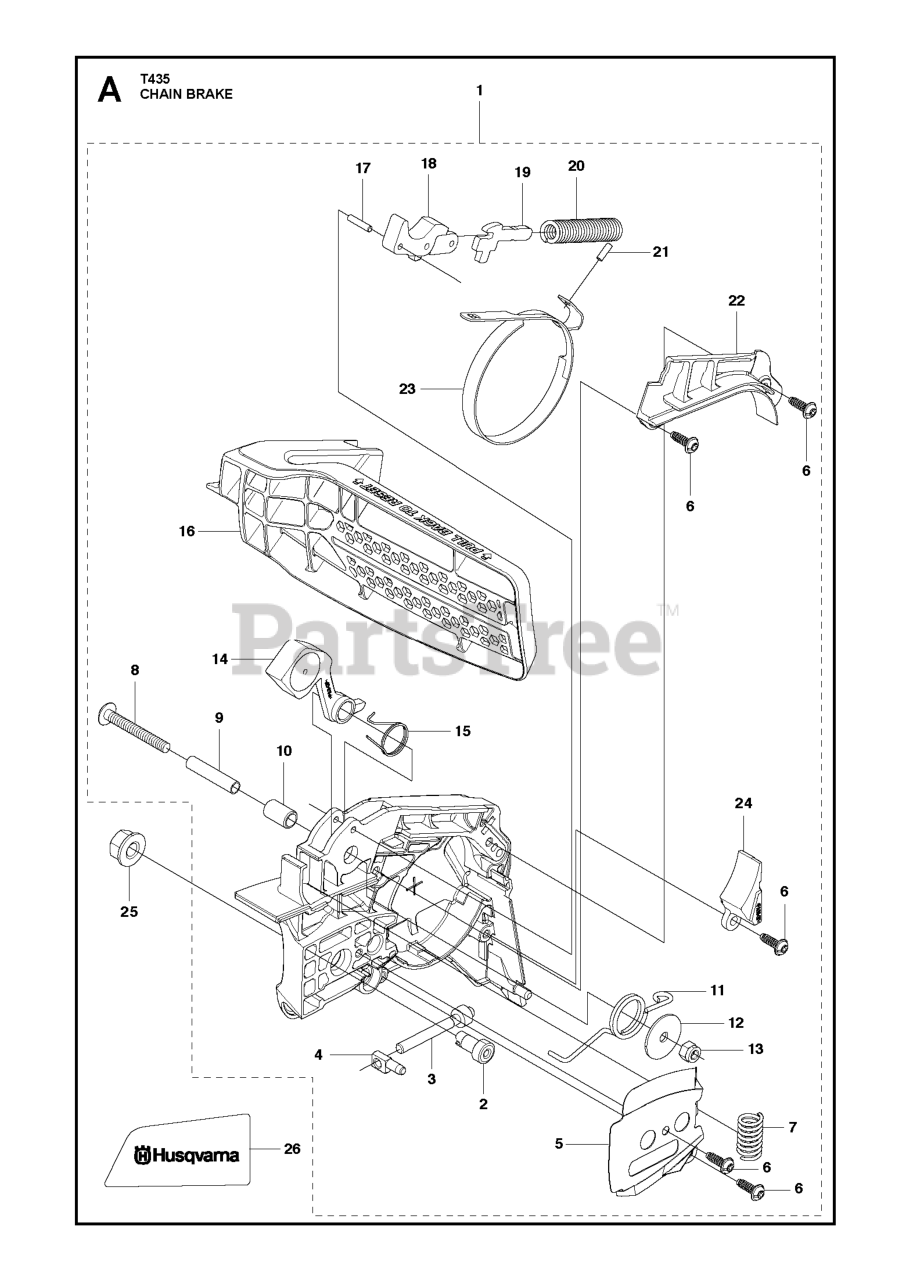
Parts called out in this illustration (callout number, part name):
1	CLUTCH COVER ASSY T435
6	SCREW
8	SCREW
9	SPACER, INNER
11	RETURN SPRING
12	WASHER
15	SPRING
17	ROLLER
18	BRAKE LEVER
19	ARM
20	SPRING
21	ROLLER
22	COVER LID GRAY
22	COVER BRAKE
23	BRAKE BAND
25	NUT FLANGE
